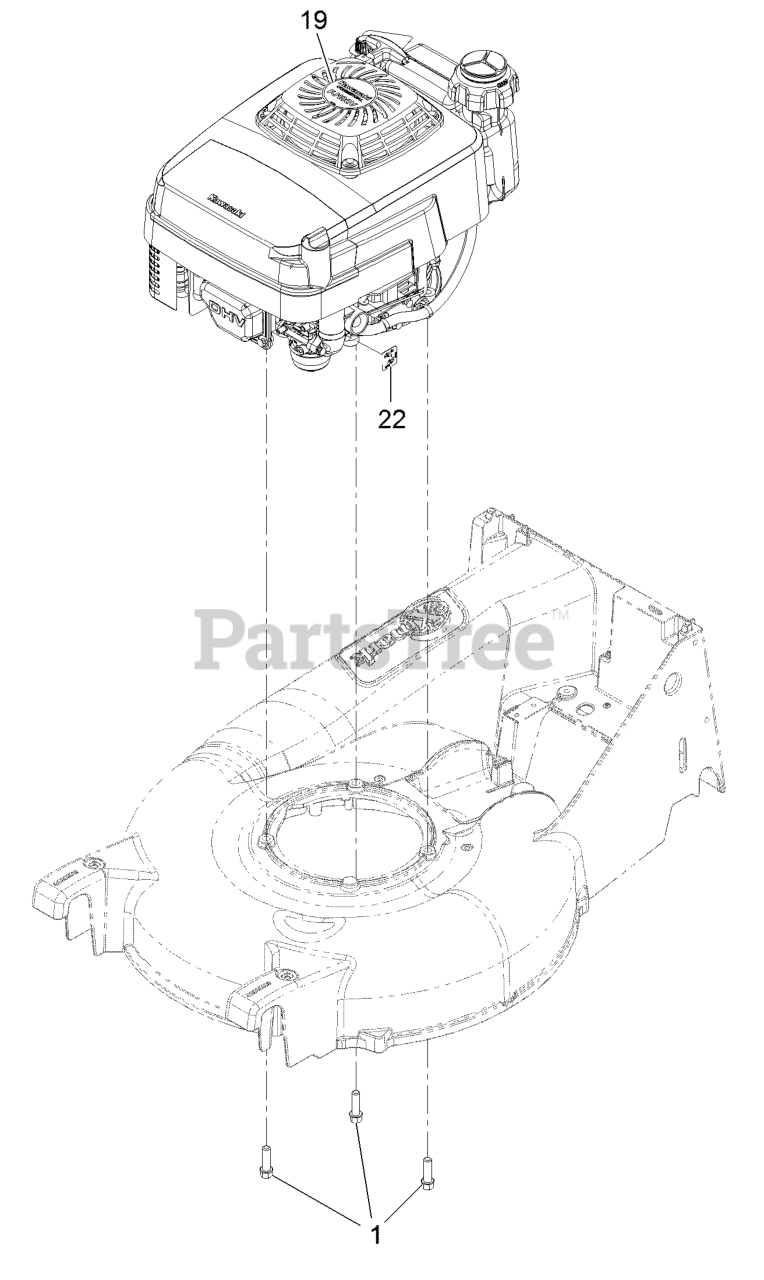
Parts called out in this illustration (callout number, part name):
1	Screw-HWH 3/8-16 X 1 1/4 Taptite
19	Decal-Recoil
22	Decal-Primer
